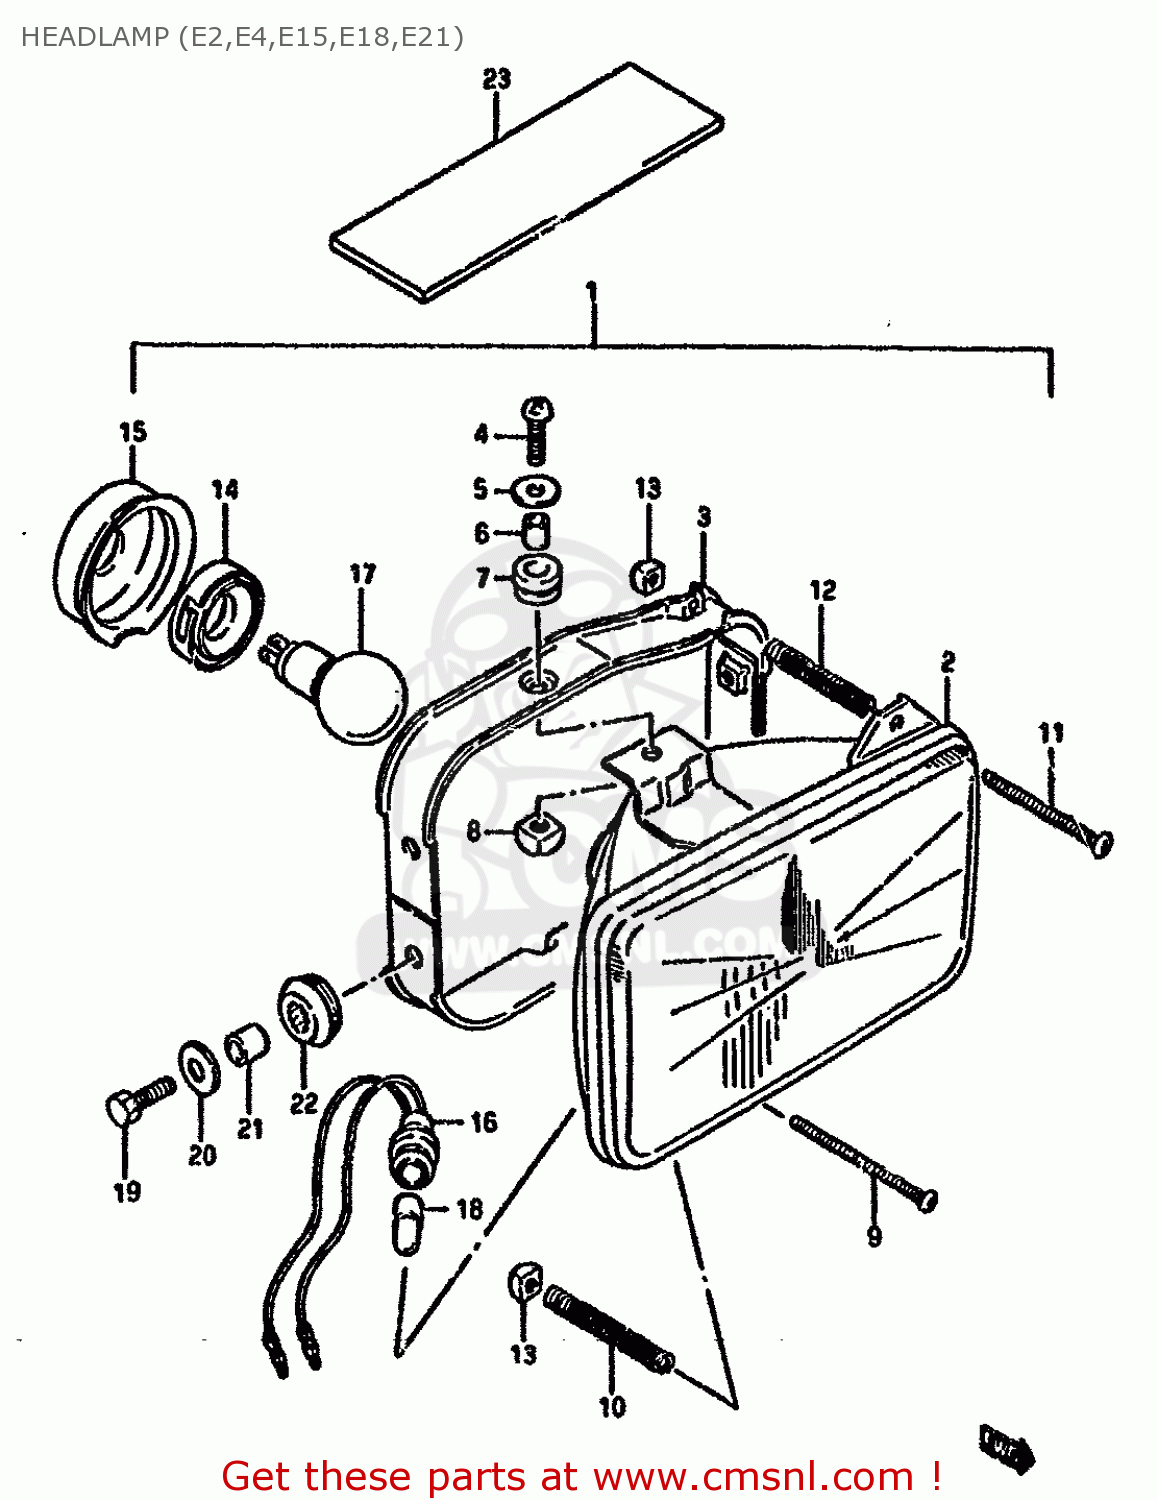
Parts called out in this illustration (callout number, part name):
1	HEADLAMP ASSY
2	LAMP UNIT
3	HOUSING
4	SCREW(5X14)
5	WASHER
6	SPACER
7	CUSHION
8	NUT
9	SCREW,HEADLAMP ADJUST
10	SPRING
11	SCREW,HEADLAMP ADJUST
12	SPRING
13	NUT
14	HOLDER,BULB
15	COVER,SOCKET
16	SOCKET,PARKING
17	BULB(12V45/40W)
18	BULB(12V4W)
19	BOLT
20	WASHER (6.5X20X1.2)
21	SPACER (6.1X9X9)
22	CUSHION
23	CUSHION
